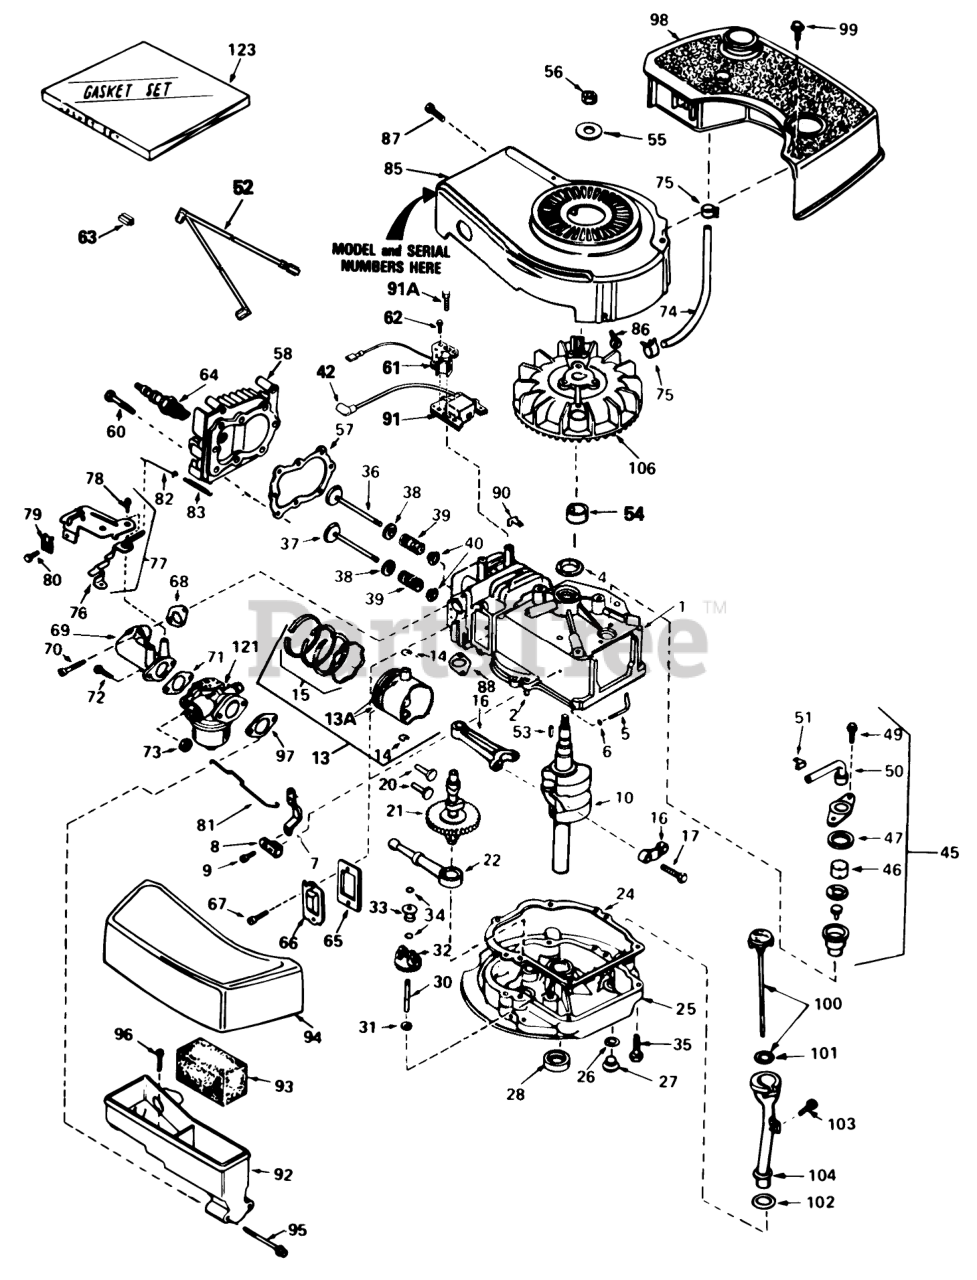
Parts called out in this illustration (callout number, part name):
1	Cylinder Assy. (Incl. #2 & 4)
2	Pin-Dowel
4	Seal-Oil
5	Rod, Governor (Incl. #6)
6	Washer-Flat
7	Governor Lever
8	Clamp-Lever, Governor
9	Screw
10	Crankshaft
13	Piston, Pin & Ring Assy. (Std.)(Incl. #13A, 14 & 15)
13	Piston, Pin & Ring Assy. (.010 oversize)(Incl. #13A, 14 & 15)
13	Piston, Pin & Ring Assy. (.020 oversize)(Incl. #13A, 14 & 15)
13A	Piston & Pin Assy. (Std.)(Incl. #14)
13A	Piston & Pin Assy. (.010 oversize)(Incl. #14)
13A	Piston & Pin Assy. (.020 oversize)(Incl. #14)
14	Ring-Retaining, Piston Pin
15	Ring Set (Std.)
15	Ring Set (.020" OS)
15	Ring Set (.010" OS)
16	Rod Assy., Connecting (Incl. #17)
17	Bolt-Rod, Connecting
20	Lifter-Valve
21	Camshaft(Mech.Comp. Release)
22	Oil Pump ASM
24	Gasket, Mounting
25	Flange Assy., Mounting (Incl. #26 thru 30)
26	Gasket-Oil Drain
27	Plug Oil Drain
28	Seal Oil
30	Shaft-Governor
31	Washer-Flat
32	Gear Assy., Governor (Incl. #31)
33	Spool-Governor
34	Ring-Retaining
35	Screw (1/4-20 x 1-1/4)
36	Valve, Intake (Std.)(Incl. #40)
36	Valve, Intake (1/32" oversize)(Incl. #40)
37	Valve, Exhaust (Std.)(Incl. #40)
37	Valve, Exhaust (1/32" oversize)(Incl. #40)
38	Cap-Upper Valve Spring
39	Spring-Valve
40	Cap-Valve, Spring
42	Cover-Spark Plug
45	Breather Assy. (Incl. #46 thru 51)
46	Element-Breather
47	Gasket-Breather
49	Screw (10-24 x 9/16)
50	Tube, Breaker
51	Clip, Breather
52	Wire-Ground
53	Key-Flywheel
55	Washer-Belleville
56	Nut-Flywheel
57	63573 GIL 42 SNWTHW
58	Head-Cylinder
60	Screw (5/16-18x1-1/2)
61	Coil, Alternator
62	Screw (8-32x27/64)
63	Connector-Body
64	Plug, Spark (J17LM or equiv.)
64	Plug, Spark (Champion RCJ-8)
65	Gasket-Breather
66	Cover-Valve
68	Gasket-Intake
69	Pipe, Intake (Incl. No. 68)
70	Screw (1/4-20 x 1)
71	Gasket-Carburetor
72	Screw (1/4-28 x 7/8)
73	Nut and Lock Washer (1/4-28)
74	Line-Fuel
75	Clamp-Line, Fuel
76	Lever Control
77	Control Assy., Speed (Incl. #76 & 78)
78	Screw, Hex Washer Hd Shoulder Self-Tap
79	Conduit
80	Screw (10-32 x 3/8)
81	Link-Throttle
82	Link Governor Spring
83	Spring Governor
85	Housing-Blower
86	Screw (1/4-20x19/32)
87	Screw (10-24 x 9/16)
88	Gasket Exhaust
90	Clip-Wire
91	Lamination & Coil Assy. (Solid State)(Incl. #42)
91A	Screw
92	Body Air Cleaner
93	Filer, Air
94	Cove, Air Cleaner
95	Screw Fil Hd.
96	Screw, Hex Hd.
97	Gasket-Air Cleaner
98	Tank-Fuel
99	Screw (10-32 x 35/64)
100	Dipstick, Oil (Incl. #101)
103	Screw (10-32 x 1/2)
104	Tube-Oil Fill
106	Flywheel
121	Carburetor (Incl. #71)
123	Gasket Set
